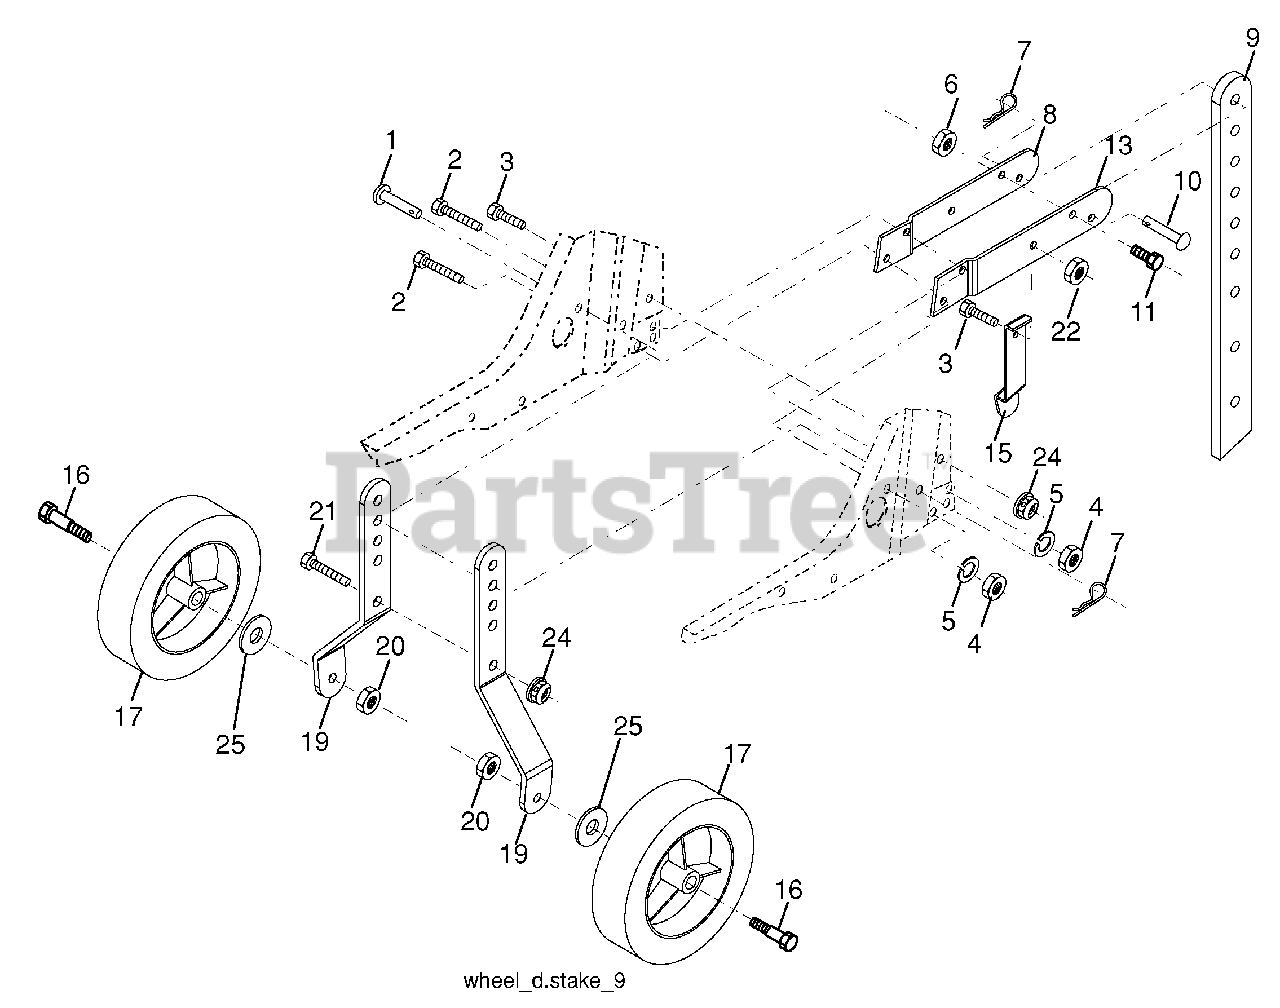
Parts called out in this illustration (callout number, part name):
1	Pin, Clevis
2	Bolt, Hex Head 5/16-18 x 1-1/4
3	Bolt, Hex Head 5/16-18 x 3/4
4	Nut, Hex 5/16-18
5	Washer, Lock 5/16
6	Locknut, w/washer 3/8-16
7	Clip, Hairpin
8	Support, Depth Stake, R.H.
9	Stake, Depth
10	Pin, Clevis
11	Bolt, Hex 3/8-16 x 1-3/4
13	Support, Depth Stake, L.H.
15	Spring, Stake
16	Bolt, Shoulder
17	Wheel
19	Bracket, Wheel
20	Locknut, Crown 3/8-16
21	Bolt, Hex Head 5/16-18 x 1
22	Locknut, w/insert 5/16-18
24	Locknut, Flange 5/16-18 unc
25	Washer 17/32 x 7/8 x 16 Ga.
